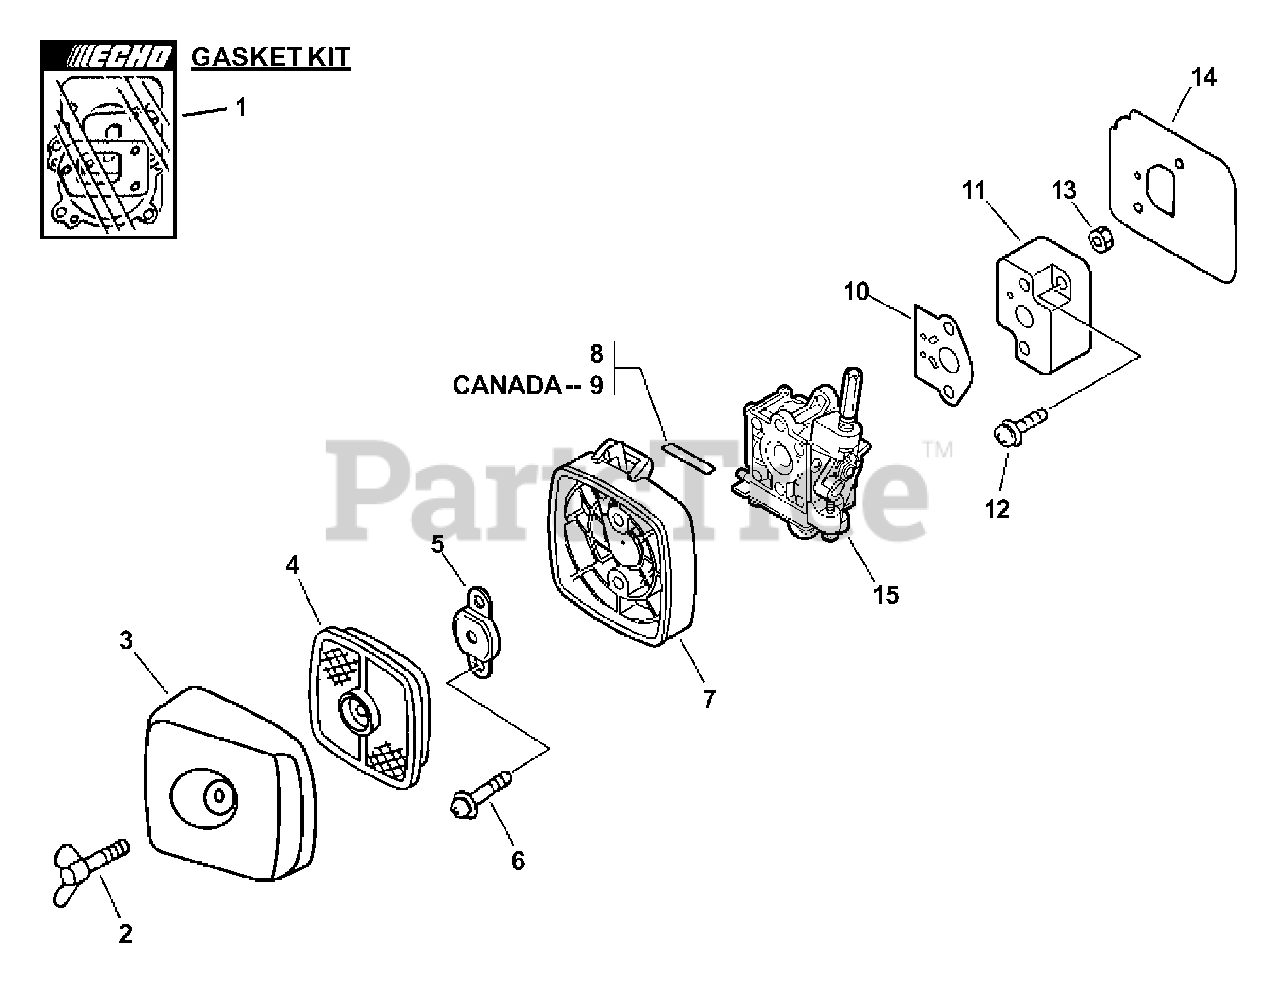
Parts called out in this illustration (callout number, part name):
1	GASKET KIT
2	BOLT, WING 5×20
3	COVER, AIR FILTER - GRAY
4	FILTER, AIR - SINGLE LAYER
5	PLATE, PREVENT
6	SCREW 5×65
7	CASE, AIR FILTER - GRAY
8	LABEL, CHOKE
9	LABEL, CHOKE
10	GASKET, CARBURETOR
11	INSULATOR, INTAKE
12	SCREW 5×20
13	NUT M5
14	HEAT SHIELD, INTAKE
15	CARBURETOR
